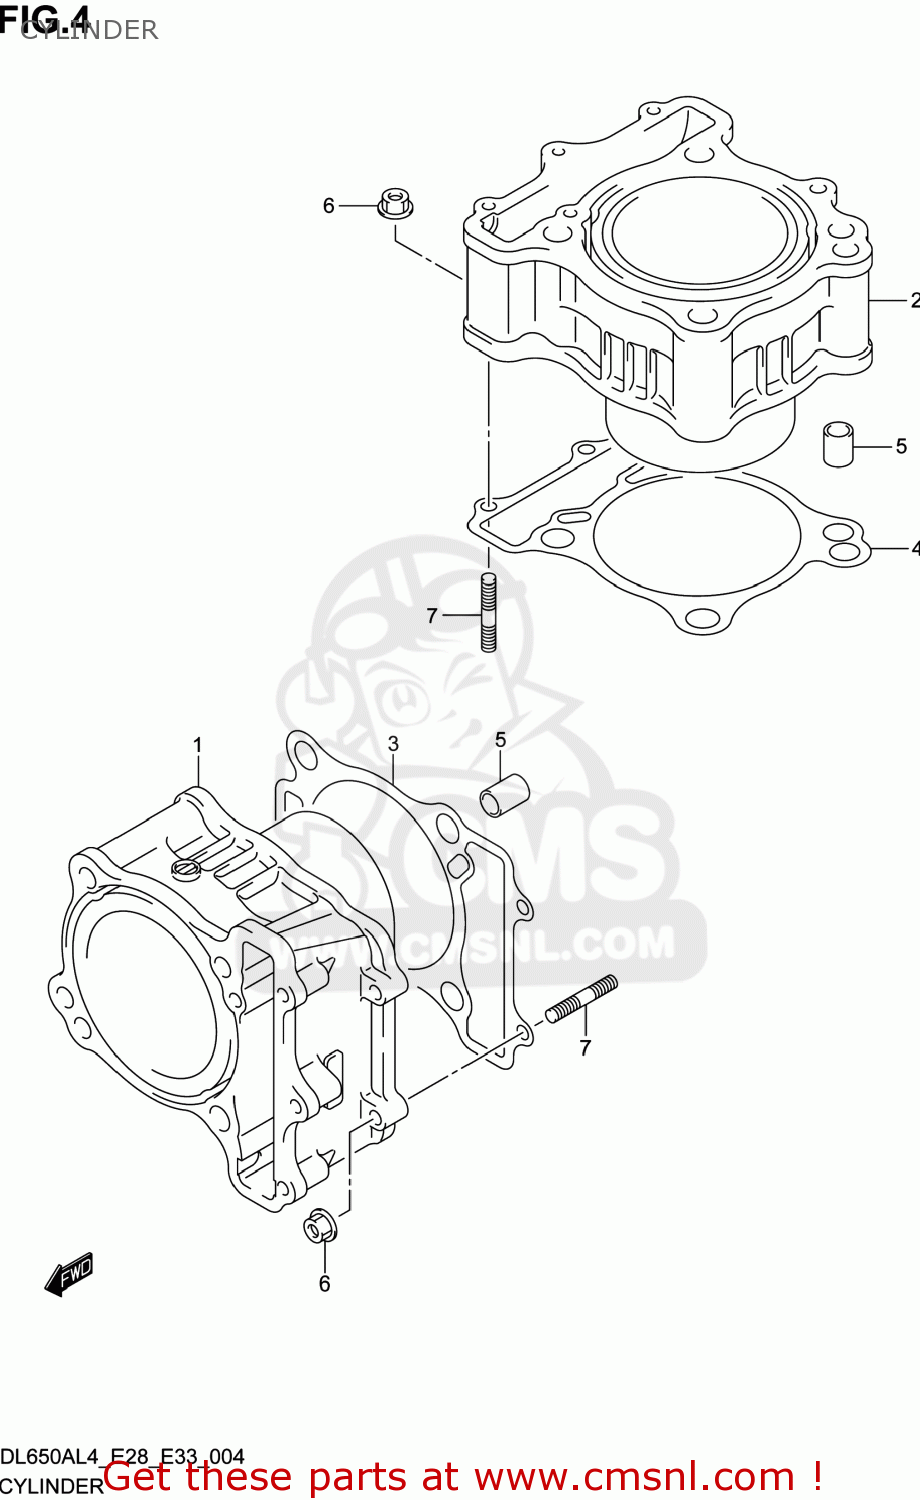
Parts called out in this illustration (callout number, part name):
1	CYLINDER,FR
2	CYLINDER,RR
3	GASKET,CYLINDER FR (NAS)
4	GASKET,CYLINDER RR (NAS)
5	PIN
6	NUT
7	BOLT,STUD
